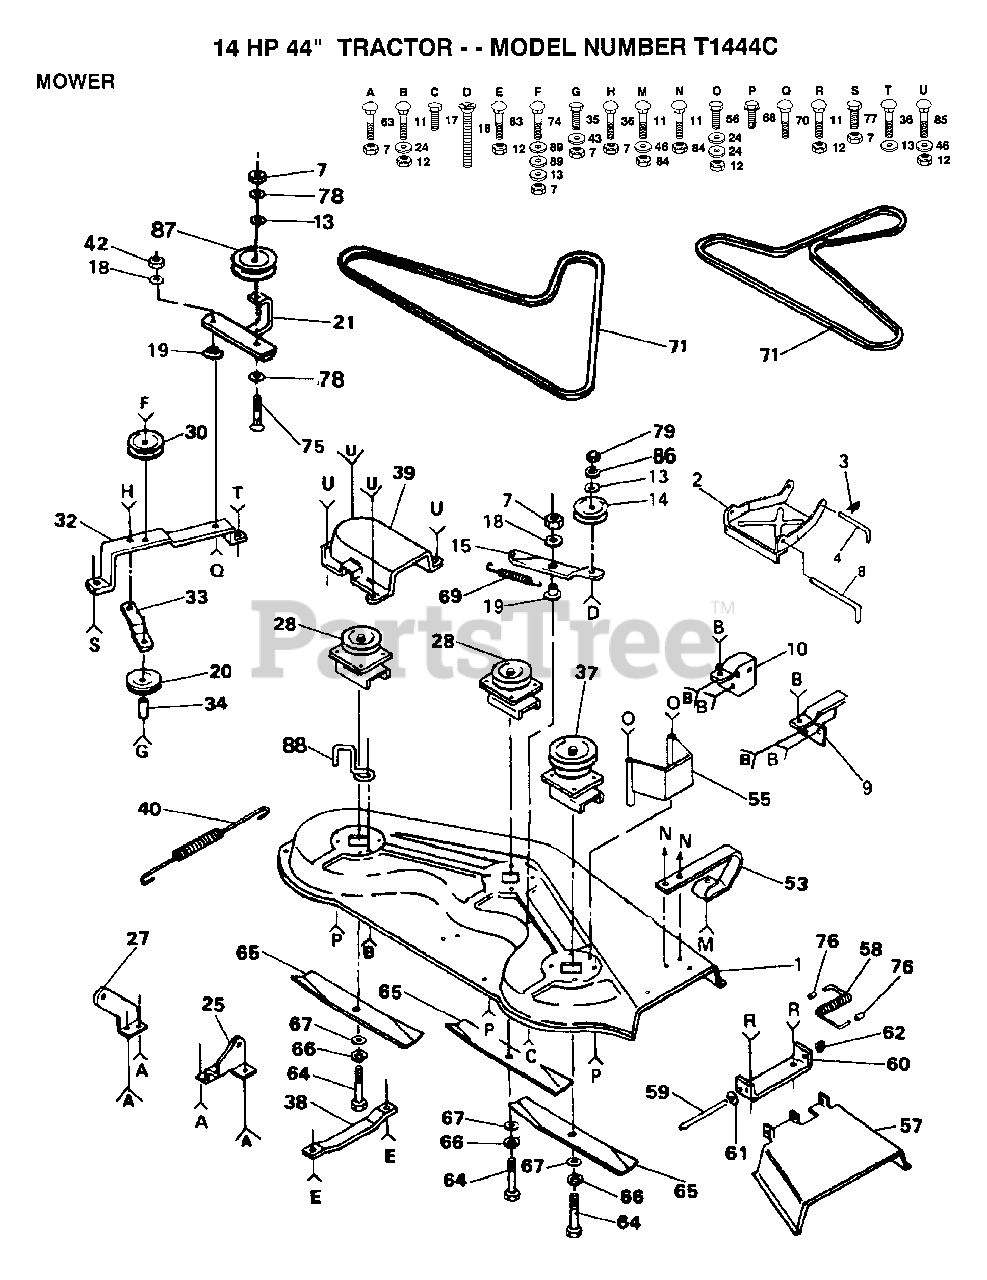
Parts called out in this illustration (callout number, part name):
2	"STOP, LINK PARAL"
3	SPRING.RETAINER
4	"ROD, FRT. PARAL T"
8	HINGE PIN T
9	BRACKET RH YT
10	BRACKET LH YT
11	BOLT
13	WASHER
14	IDLER.FLAT.GTV
15	ARM-IDLER YT
16	SCREW YT
18	"WASHER, WEAR LT"
19	SPACER RETAINER
20	IDLER-FLAT T
21	ARM IDLER
24	WASHER M
25	BRKT SUSP REAR RH
27	BRKT SUSP REAR LH
30	IDLER-INSIDE T
32	"SUPPORT YT, BAR"
33	BRACE-IDLER YT
34	SPACER
35	BOLT - HEX 3/8 - 16 X 3
38	RUNNER-LH M
39	GUARD YT
40	"SPRING.EXT.8.5"""
42	LOCKNUT
43	WASHER
46	WASHER
55	GUARD BELT HYT
56	BOLT
57	DEFLECTOR SHIELD
59	ROD-HINGE T
61	WASHER
62	NUT PUSH M
63	BOLT
64	BOLT.3/8-24X1-1/2
67	WASHER
68	SCREW
70	BOLT
71	BELT-V.79.1.MWR
74	BOLT
75	BOLT
76	CAP-SLEEVE LT
77	BOLT
78	WASHER
79	NUT.HEX.3/8-16UNC
83	BOLT
86	LOCKWASHER
87	PULLEY IDLER
88	BELT RETIANER
89	WASHER
